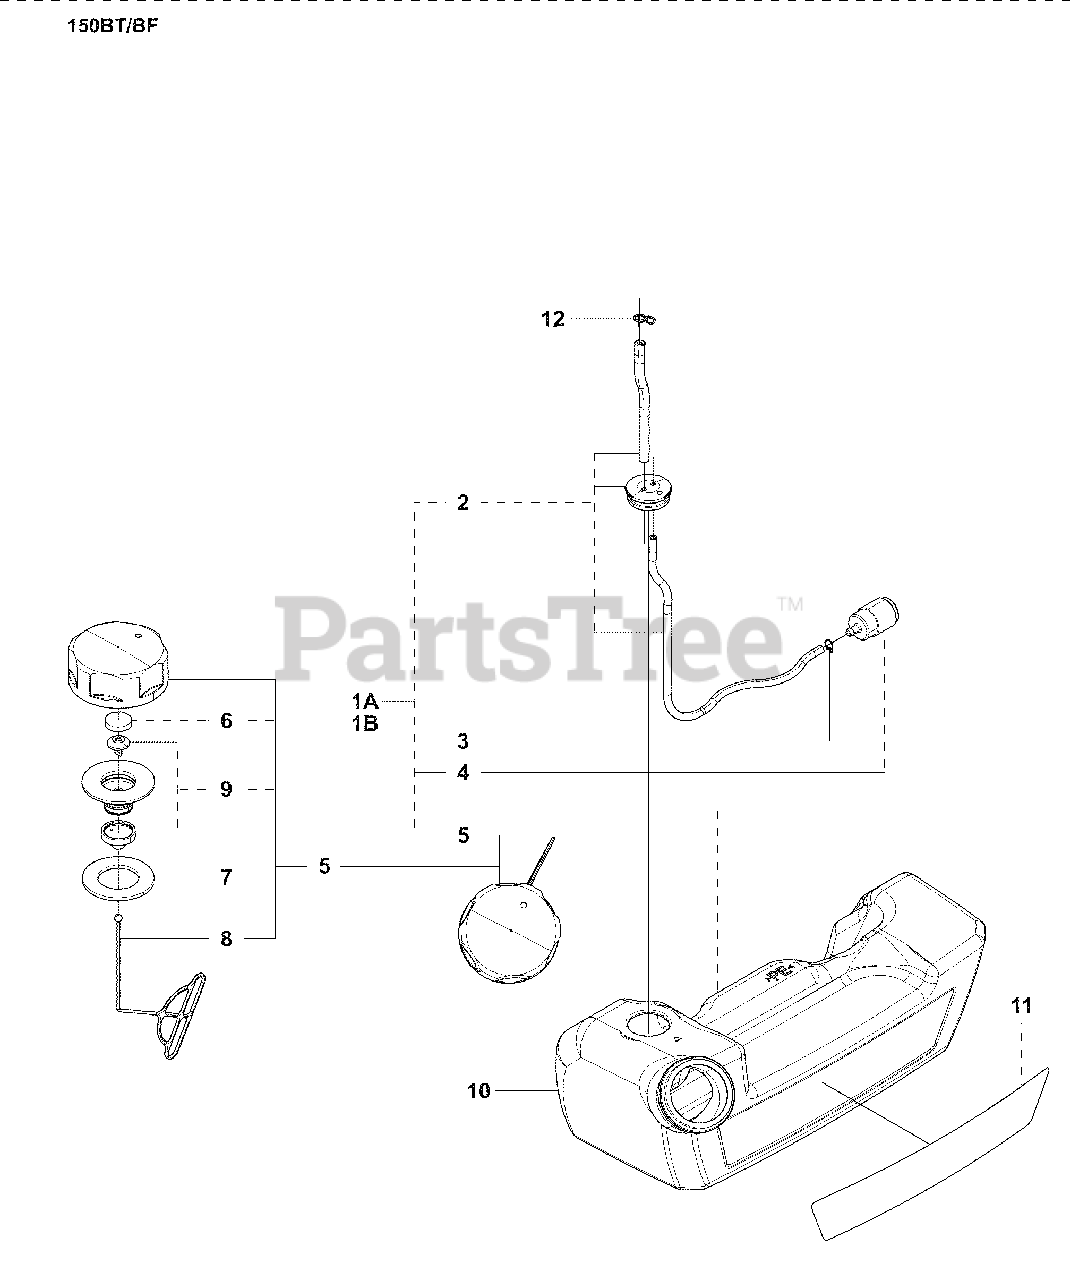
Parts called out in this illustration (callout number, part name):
1A	TANK ASSY
1B	TANK ASSY
2	PIPE C
3	CLIP
4	FILTER
5	CAP-A
6	FILTER
7	PACKING
9	HOLDER-A
12	CLIP
